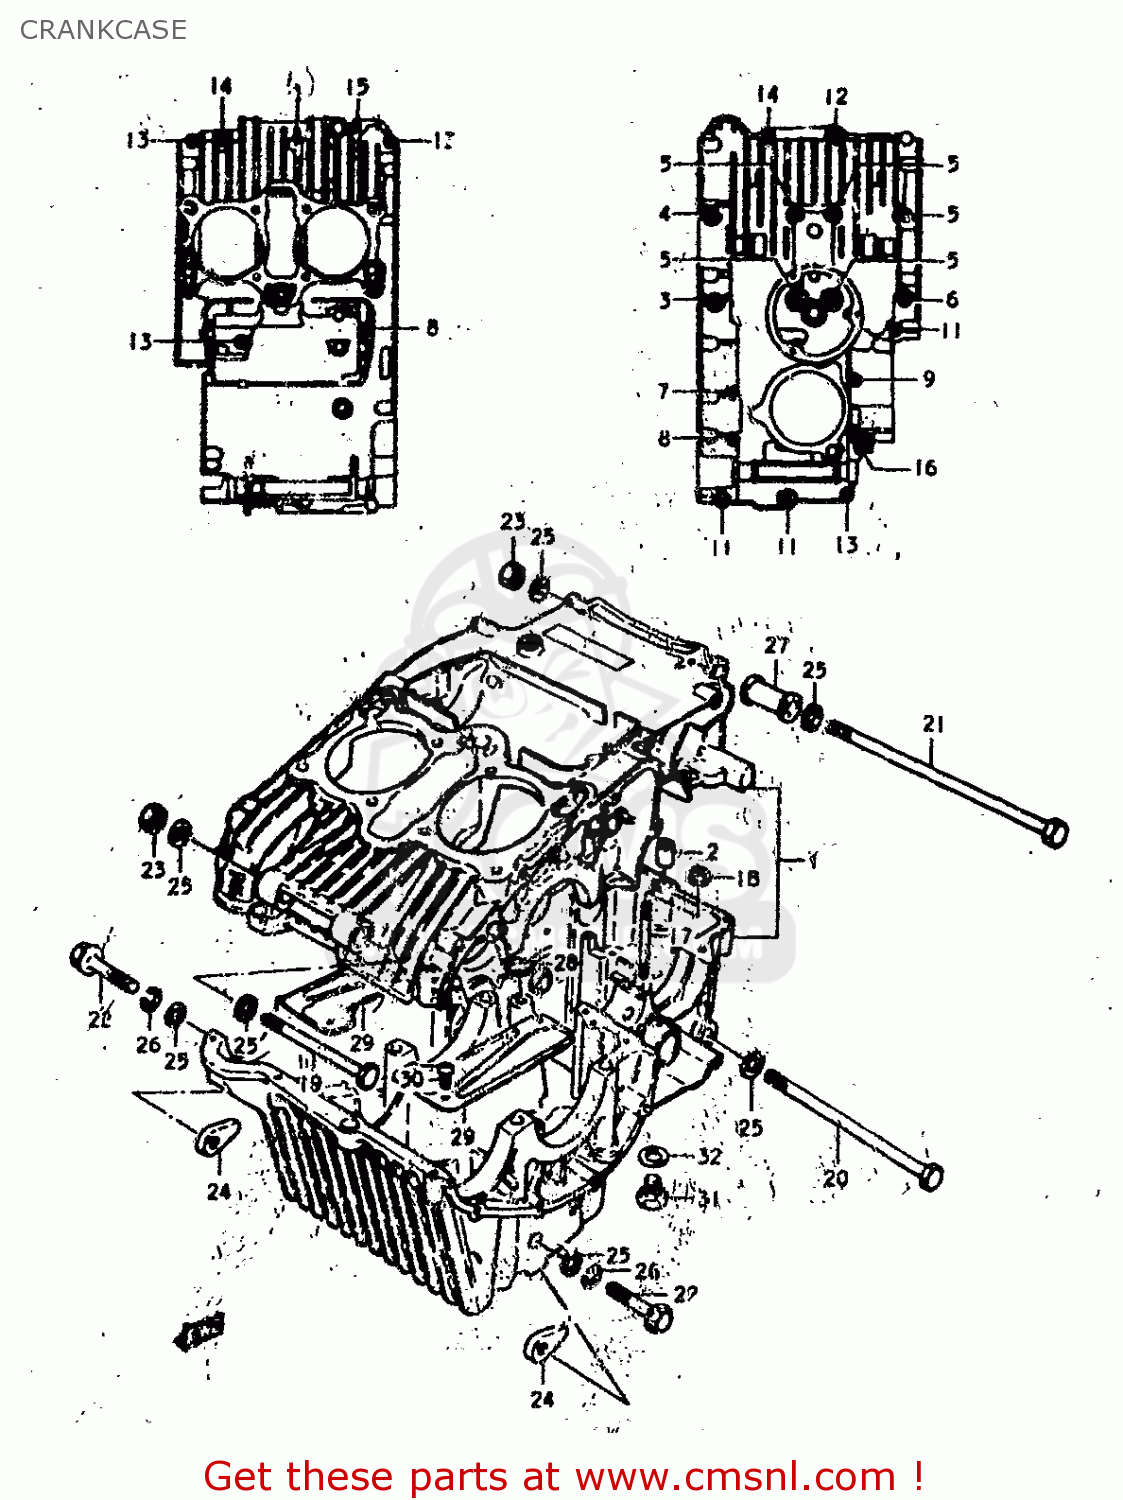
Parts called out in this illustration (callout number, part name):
1	CRANKCASE SET
2	PIN
3	BOLT
4	BOLT (8X95)
5	BOLT 8X90
6	BOLT
7	BOLT
8	BOLT (6X90)
9	BOLT (6X70)
10	BOLT 6X65
11	BOLT (6X60)
12	BOLT,UNDER
13	BOLT
14	BOLT 6X35
15	BOLT
16	BOLT (8X45)
17	STUD BOLT
18	NUT
19	BOLT
20	BOLT 10X160
21	BOLT 10X265
22	BOLT 10X45
23	NUT
24	NUT
25	WASHER
26	LOCK WASHER
27	SPACER,ENGINE MOUNT
28	O-RING
29	PLATE,OIL SEPARATOR
30	SCREW
31	PLUG
32	GASKET(14X19.2X2) (NAS)
